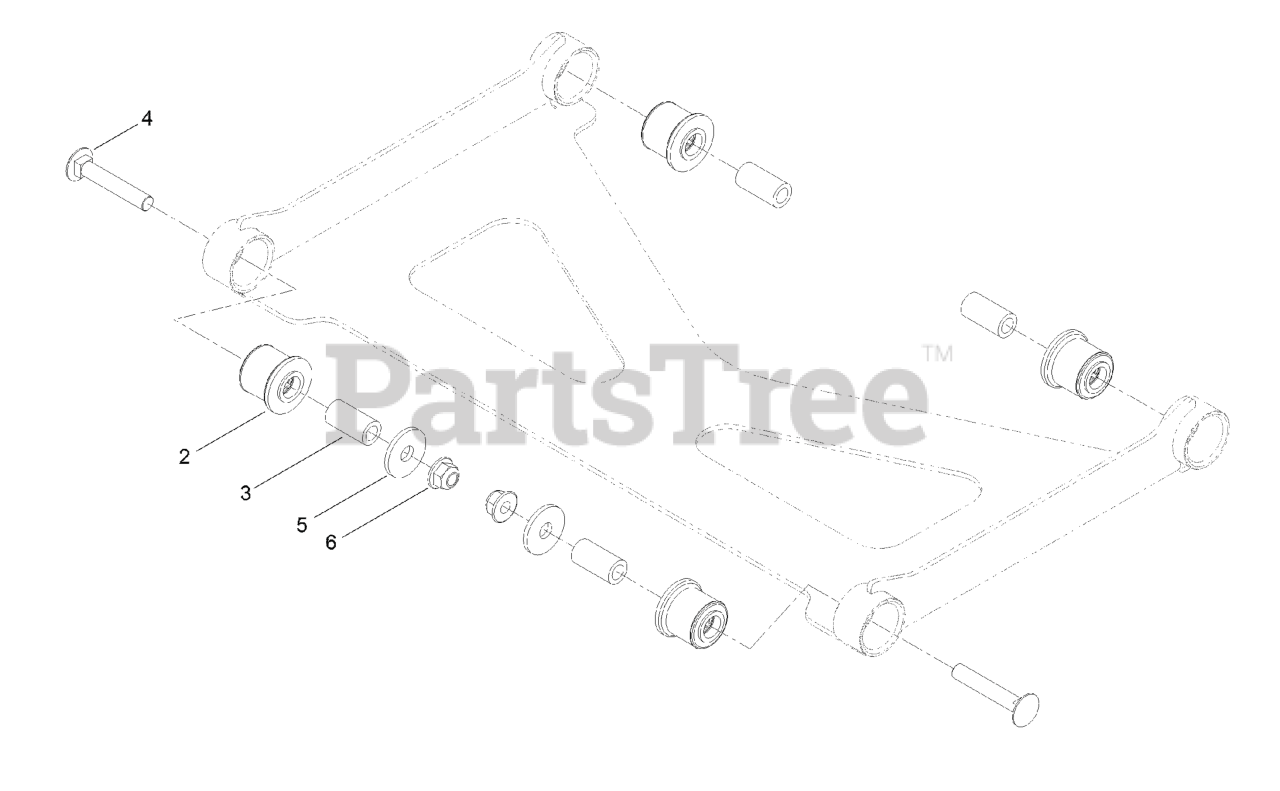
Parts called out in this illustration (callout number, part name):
2	BUSHING-RUBBER, SUSPENSION
4	Bolt-Carriage 3/8-16 X 2 1/4
5	WASHER
6	NUT-HF, NI
